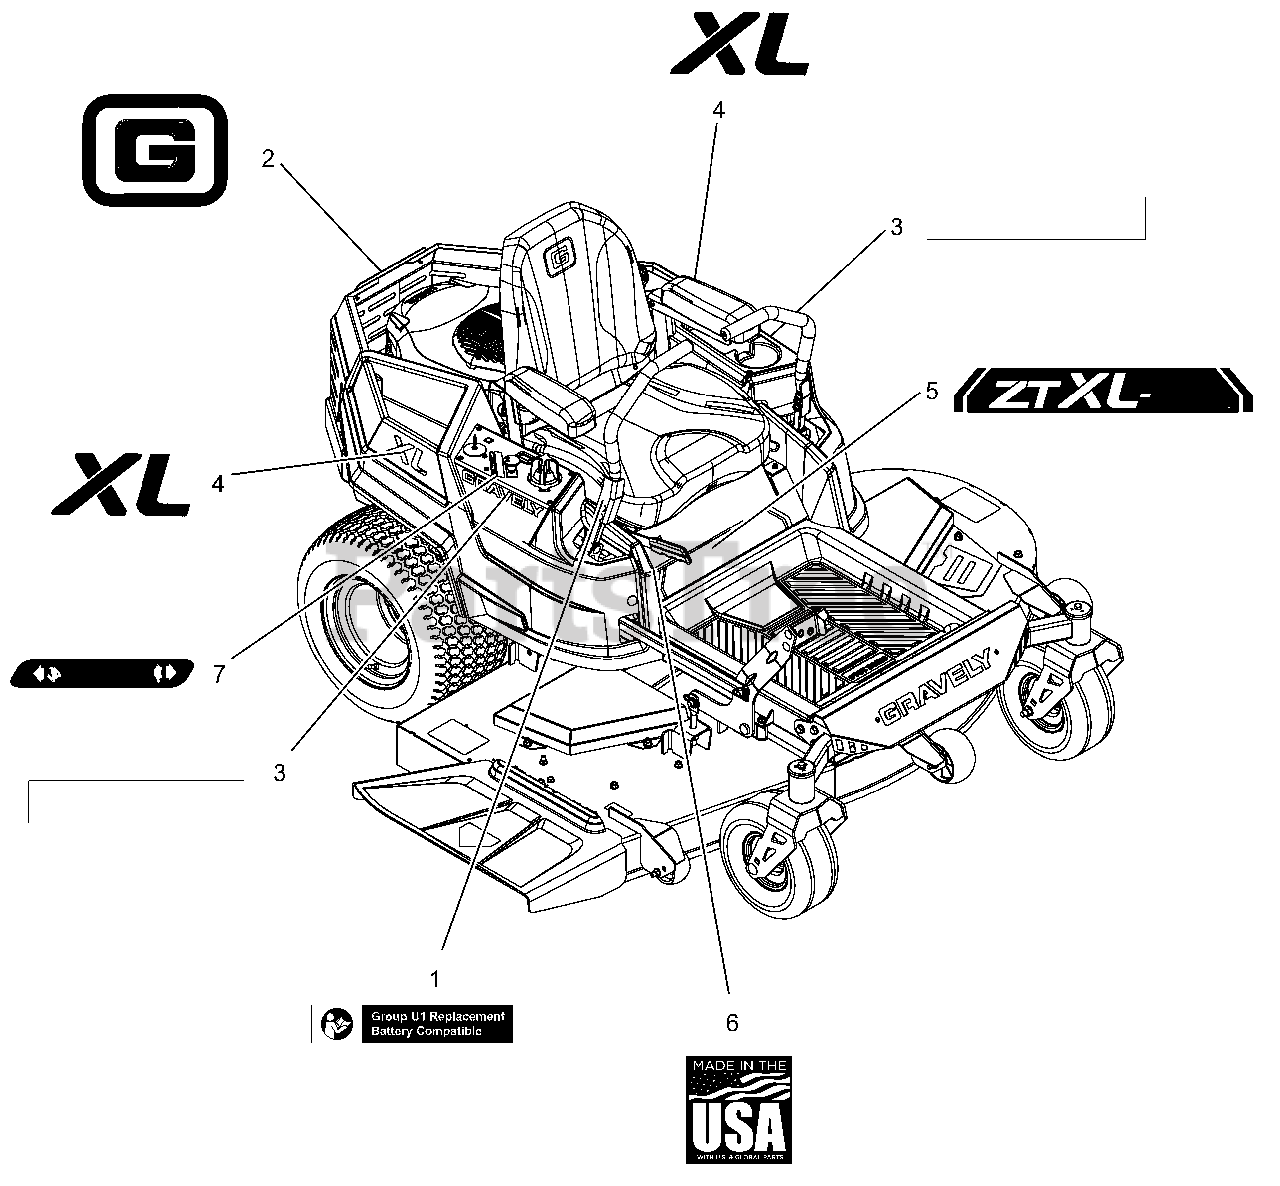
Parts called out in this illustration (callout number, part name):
1	DECAL, U1 BATTERY REPLACEMENT
2	DECAL, GRAVELY BRAND
3	DECAL, 9.5" GRAVELY LOGO
4	DECAL, "XL"
5	DECAL, ZTXL 60
6	DECAL, MADE IN USA
7	DECAL, DASH DECAL
